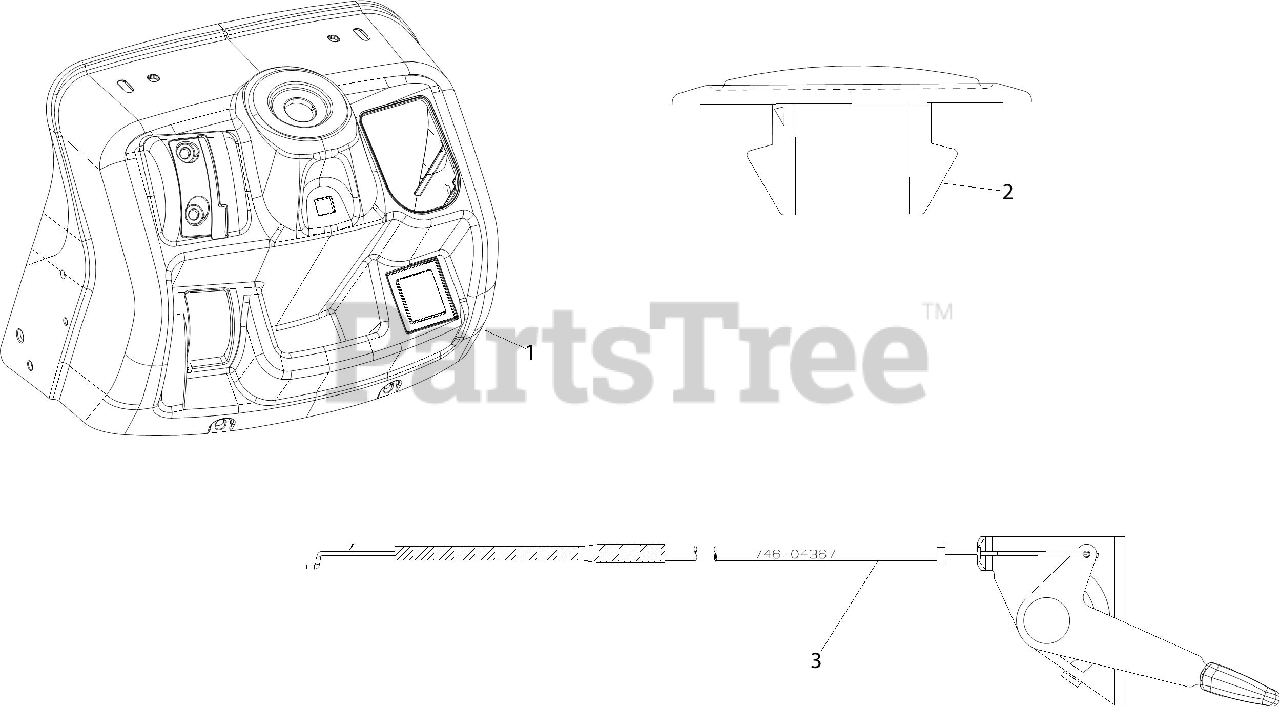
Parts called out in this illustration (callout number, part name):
1	UPPER DASH
2	CHOKE PLUG
3	THROTTLE CABLE 28" x 1.1
